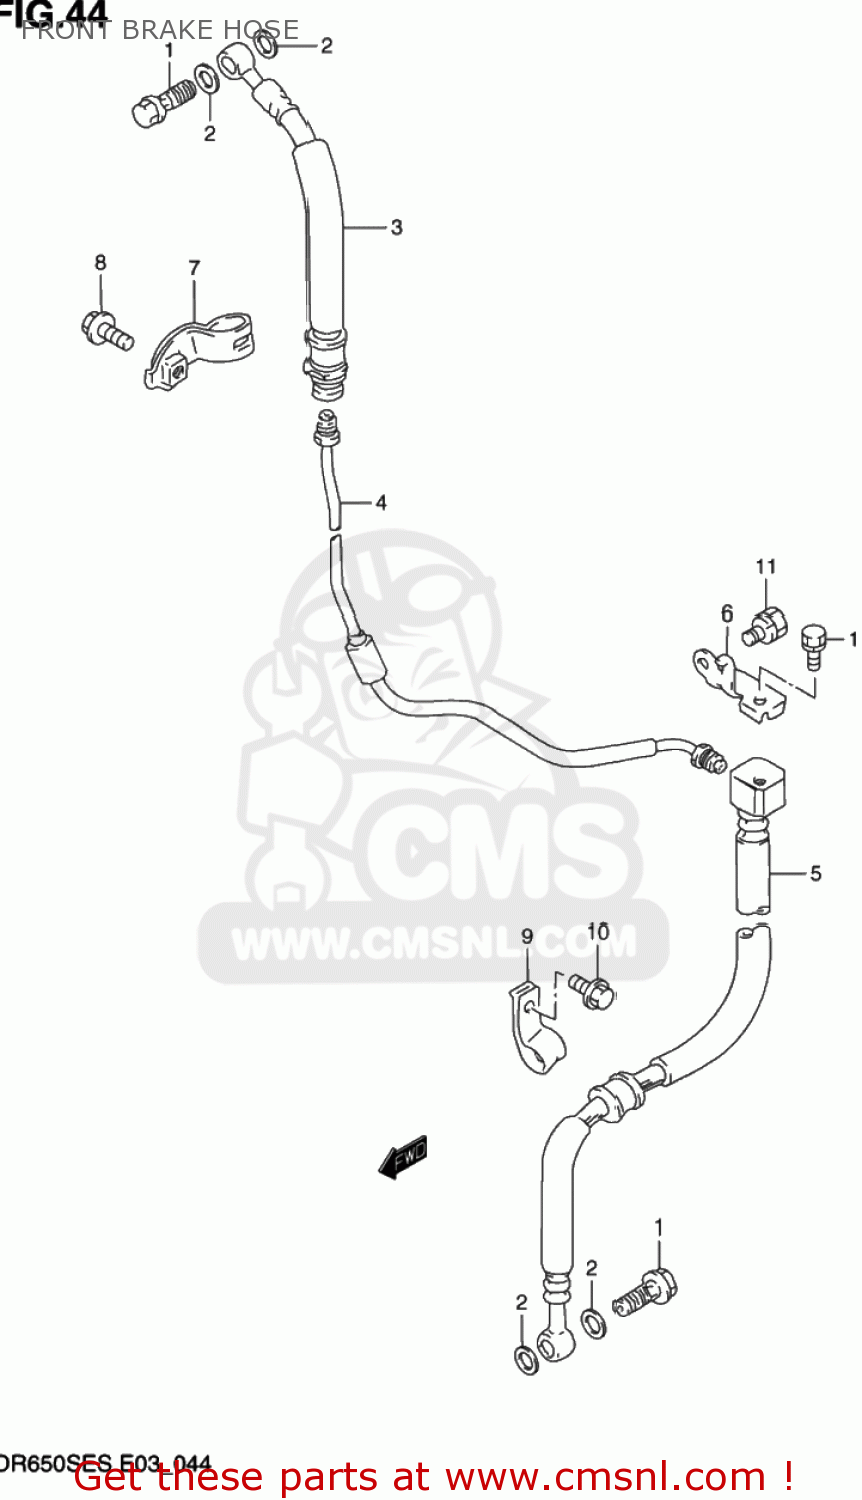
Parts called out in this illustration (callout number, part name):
1	BOLT UNION
2	WASHER(10X15X1.5)
3	HOSE COMP,FRONT BRAKE
4	PIPE,FRONT BRAKE
5	HOSE COMP,FRONT BRAKE
6	BRACKET,FRONT BRAKE HOSE
7	CLAMP COMP,FRONT BRAKE HOLDER
8	BOLT
9	CLAMP,FR BRAKE HOSE NO.2
10	BOLT
11	BOLT
